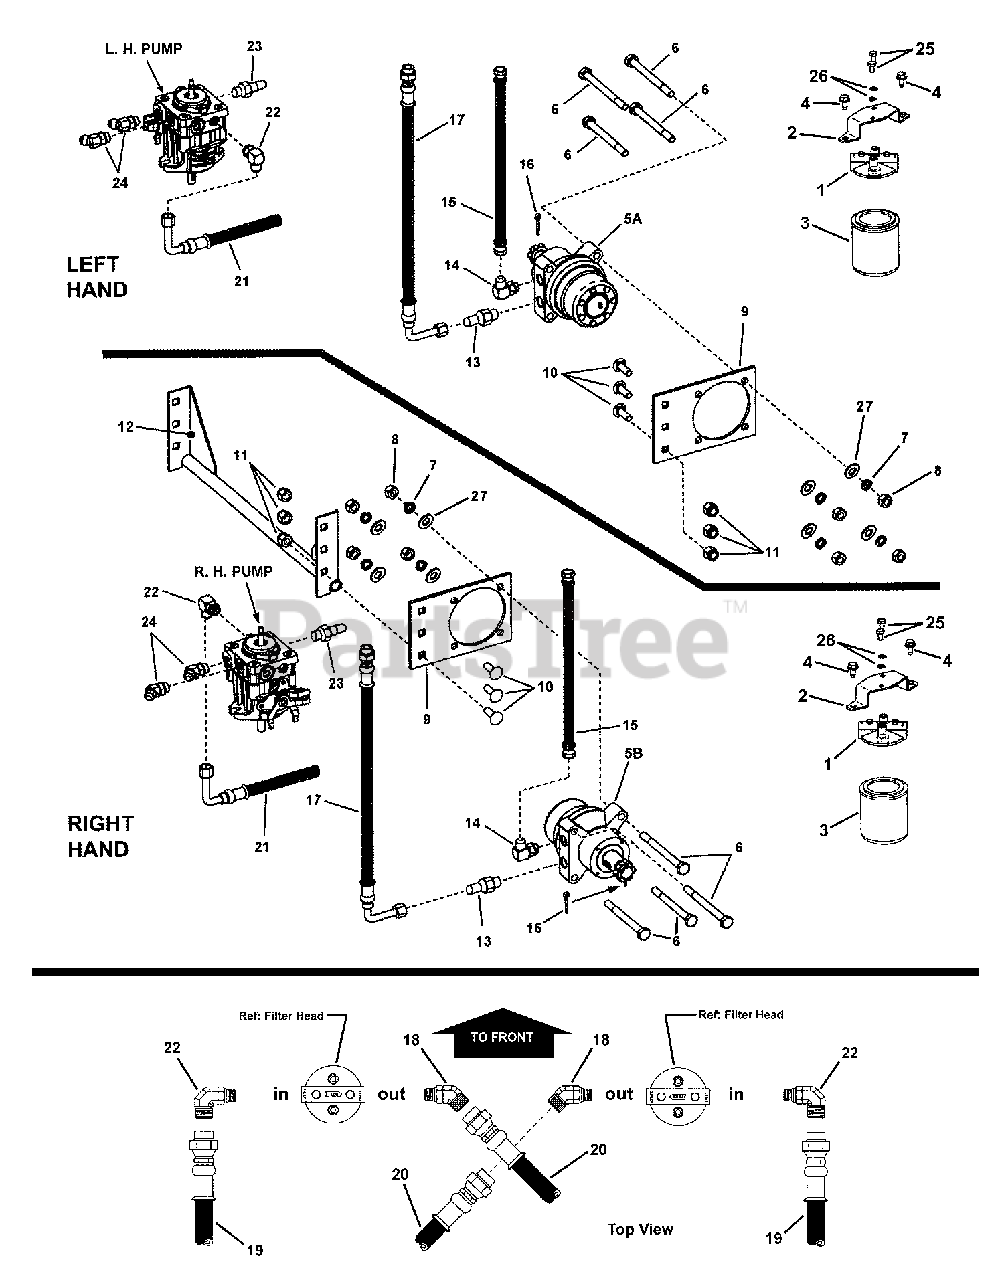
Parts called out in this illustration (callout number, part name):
1	FILTER HEAD
2	BRACKET, Filter
3	FILTER, OIL
4	SCREW, 5/16-18 x 5/8" Hex Washer Self-Tap
5A	MOTOR, Hydraulic, Left Hand
5B	MOTOR, Hydraulic, Right Hand
6	BOLT, 1/2-13 x 6" Hex Head Cap GR 5
7	WASHER, 1/2" Split Lock
8	NUT, 1/2-13 HEX
9	MOUNTING PLATE, Hydro Motor
10	BOLT, 1/2-13 x 1-1/2" Square Neck Carriage, GR 5
11	NUT, 1/2-13 Hex Nyloc
12	WELDMENT, Rear Crossbrace
13	CONNECTOR, Straight Hydraulic (Parker # 8-10 F5OLO-S)
14	CONNECTOR, 90-Degree Hydraulic (Parker # 8-10 C5OLO-S)
15	HOSE, 13-3/4" Hydraulic (Parker # F436BKJCJC080808-13-75)
16	COTTER PIN, 1/8 x 1-1/2"
17	HOSE, 17-1/2" Hydraulic (Parker # F436BKJCJ5080808-17.5)
18	CONNECTOR, 45-Degree Hydraulic (Parker #8-6 V 50L0-S)
19	HOSE, 18-1/2" (Parker R836BKJCJ9090808-18.5)
20	HOSE, 12-1/4" (Parker # R836BKJ9NR080008-12.5)
21	HOSE, 6-1/2" (Parker # R836BKJ9NR080008-6.5)
22	CONNECTOR, 90-Degree Hydraulic (Parker # 8-6 C5OLO-S)
23	CONNECTOR, Straight Hydraulic (Parker # 8-6 F5OLO-S)
24	CONNECTOR, 45-Degree Hydraulic (Parker # V5OLO-S)
25	SCREW, 1/4-20 x 1/2" Hex Head Cap, GR 5
26	WASHER, 1/4" Split Lock
27	WASHER, .531 I.D. Flat
